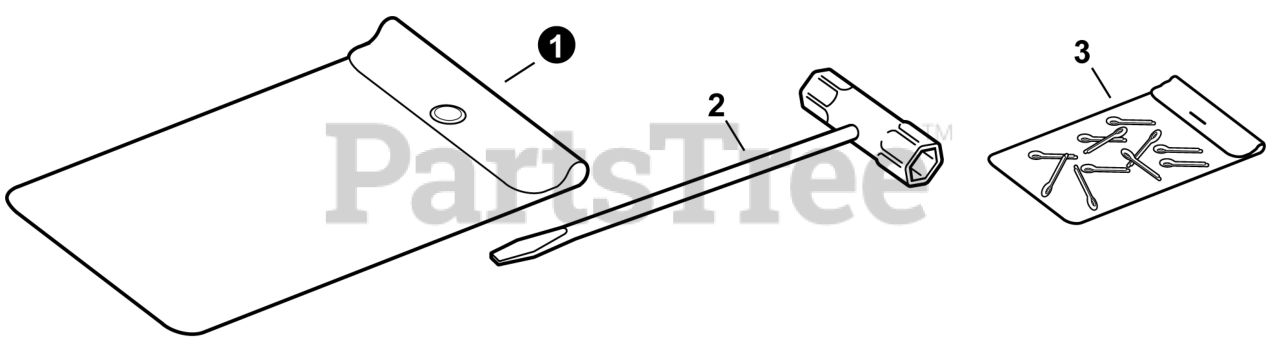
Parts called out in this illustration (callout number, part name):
1	BAG, TOOL
2	T-WRENCH
3	PIN, COTTER 2×22
